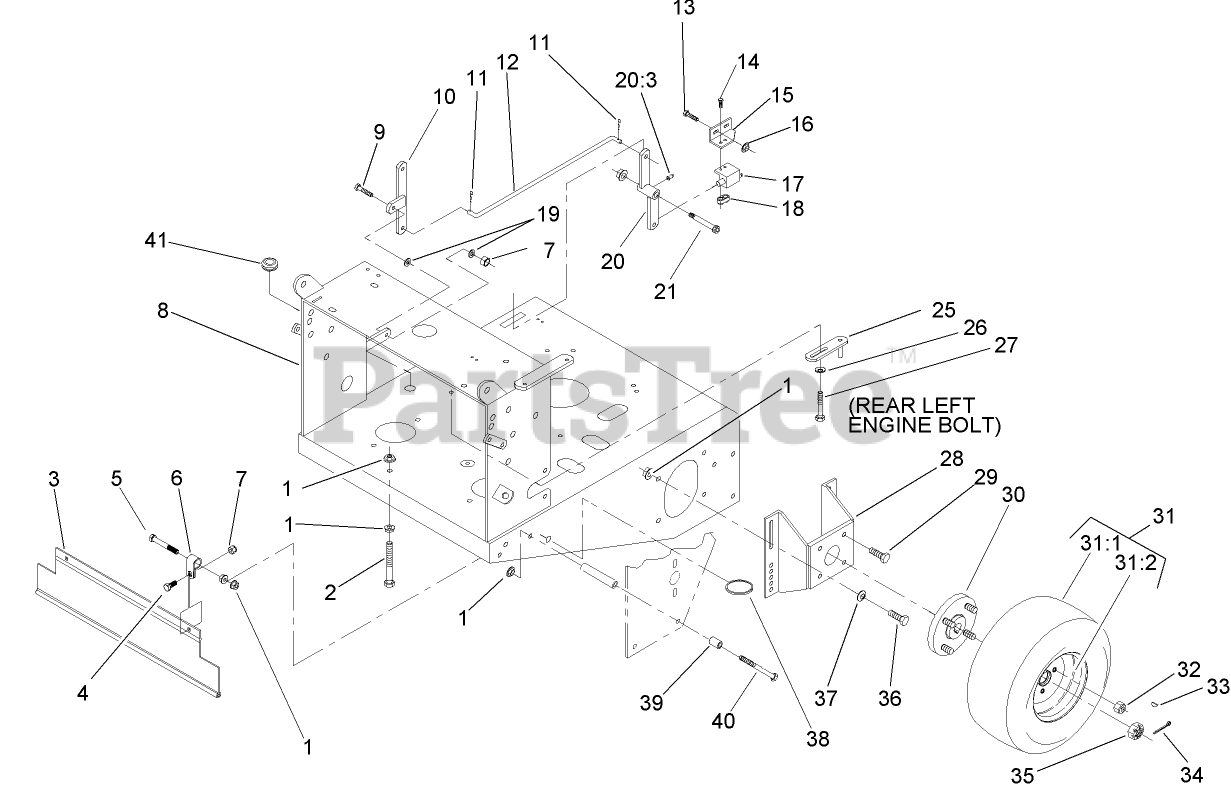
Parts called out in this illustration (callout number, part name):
1	NUT-HHF, WHIZ
2	SCREW-HH
3	Shield-Drag
4	SCREW-HH
5	SCREW-HH
6	Clip-Loom
7	NUT-LOCK, NI
8	DECK-ENGINE
9	SCREW-HH
10	BELLCRANK ASM
11	PIN-COTTER
12	Linkage-Engage, Blade
13	SCREW-HH
14	SCREW-PPH
15	Bracket-Switch, Blade
16	NUT-HF
17	SWITCH-OPEN, NORMALLY
18	PLATE-TAPPED
19	WASHER-PLAIN
20	Bellcrank ASM
20:3	FITTING-GREASE, 90 DEG
25	GUIDE-BELT
26	WASHER-SPRING
27	SCREW-HH
28	Mount-Motor
29	SCREW-HHF
30	HUB ASM W/STUDS
31	WHEEL AND TIRE ASM
31:1	Tire-Turfmaster
31:2	Wheel-Rim
32	NUT-LUG
33	Key-Woodruff
34	PIN-COTTER
35	NUT-HEX, SLOTTED
36	SCREW-HH
37	WASHER-BELLEVILLE
38	Ring-Split
39	SPACER-SHORT
40	SCREW-HH
41	GROMMET
